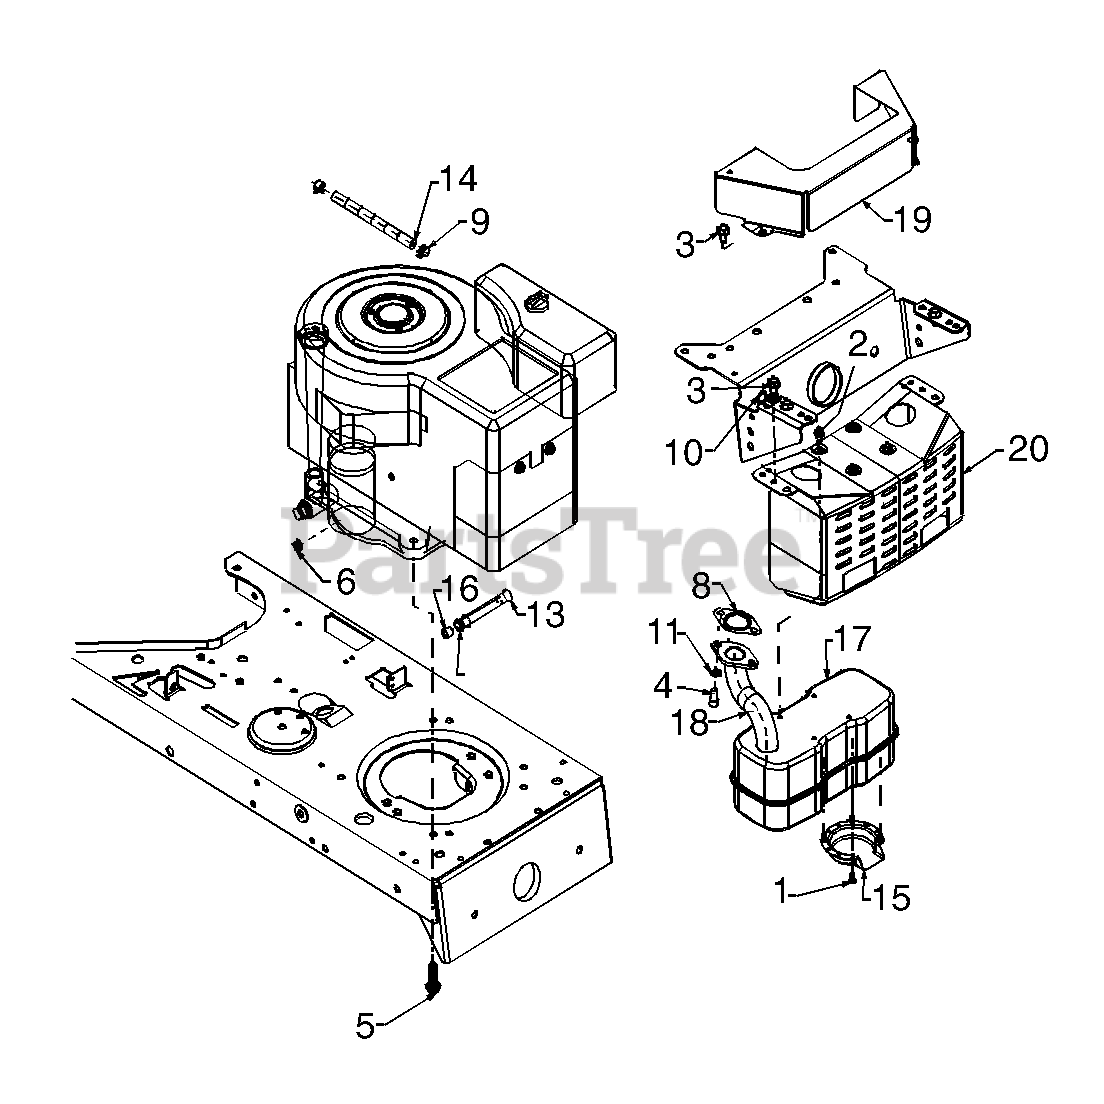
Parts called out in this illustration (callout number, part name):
1	Hex Bolt #8-32 x .38" Lg.
2	Hex Wash. Hd. TT-Scr. 1/4-20 x .5" Lg.
3	Hex Wash. Hd. TT-Scr. 5/16-18 x .62"
4	Socket Hd. Bolt 5/16-18 x .62" Lg.
5	Hex Wash. Hd. TT-Scr. 3/8-16 x 1.25"
6	Hex Sems Nut 1/4-20 Thd.
8	Exhaust Gasket
9	Hose Clamp
10	Clamp
11	Lock Washer 5/16" I.D.
13	Pipe 3/8 NPT x 3.8" Lg.
14	Fuel Line
15	Muffler Deflector
16	Hex Pipe Plug
17	Muffler
18	Exhaust Pipe
